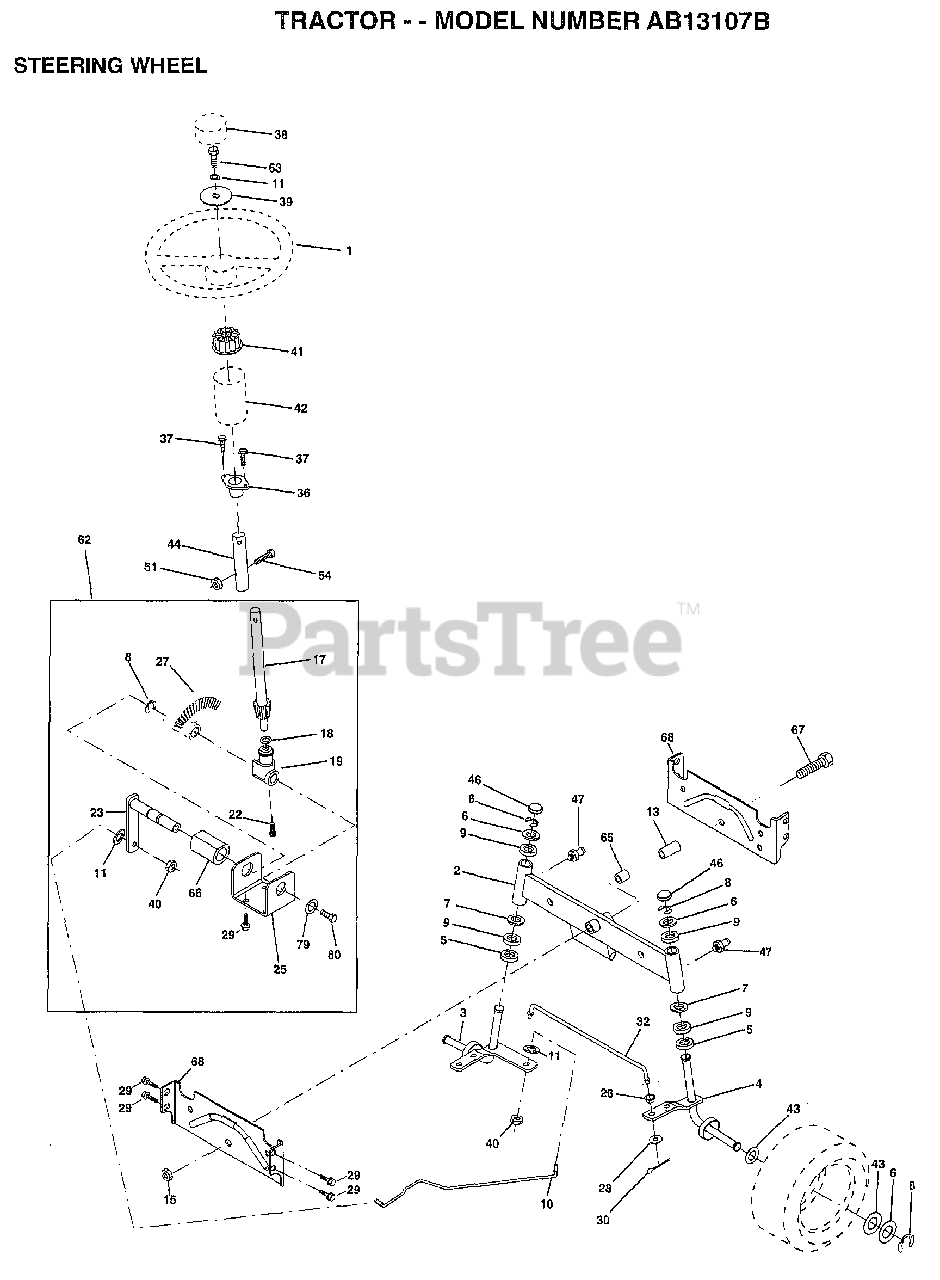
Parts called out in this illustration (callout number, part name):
2	AXLE ASM
3	SPINDLE.ASM.LH
4	"SPINDLE ASM,RH"
5	WASHER .T
6	WASHER
7	WASHER
8	RING
9	COL. SRTG. BEAR.
10	DRAGLINK-STAMPED
11	LOCKWASHER
13	BEARING AXLE
15	"NUT-LOC,FLANGE LT"
17	SHAFT ASM STEERIN
18	THRUST WASHER
19	SUPPORT.SHAFT.STEER
22	SCREW.HX.WSH.HD
23	SHAFT.ASM.PITMAN
25	BRKT-STEERING
26	BUSHING.DRAGLINK
27	GEAR SECTOR
28	WASHER
29	SCREW
30	COTTER PIN
32	TIE ROD
36	BUSHING.STEERING
37	"SCREW-TT,10-32 FL"
38	ST WHL INSERT CAP
39	WASHER T
40	GRIPCO NUT
41	ADAPTER LT
42	BOOT.STEER.PL
43	WASHER
44	EXT SHAFT STEERIN
46	CAP
47	ZERK M
51	NUT
54	BOLT
62	KIT.STEER.ASM
63	BOLT
65	SPACER AXLE
66	"BEARING-ARM,PITMA"
67	BOLT
68	BRACE AXLE
79	WASHER
80	BOLT.HX.NYLON3/8-16X3/
